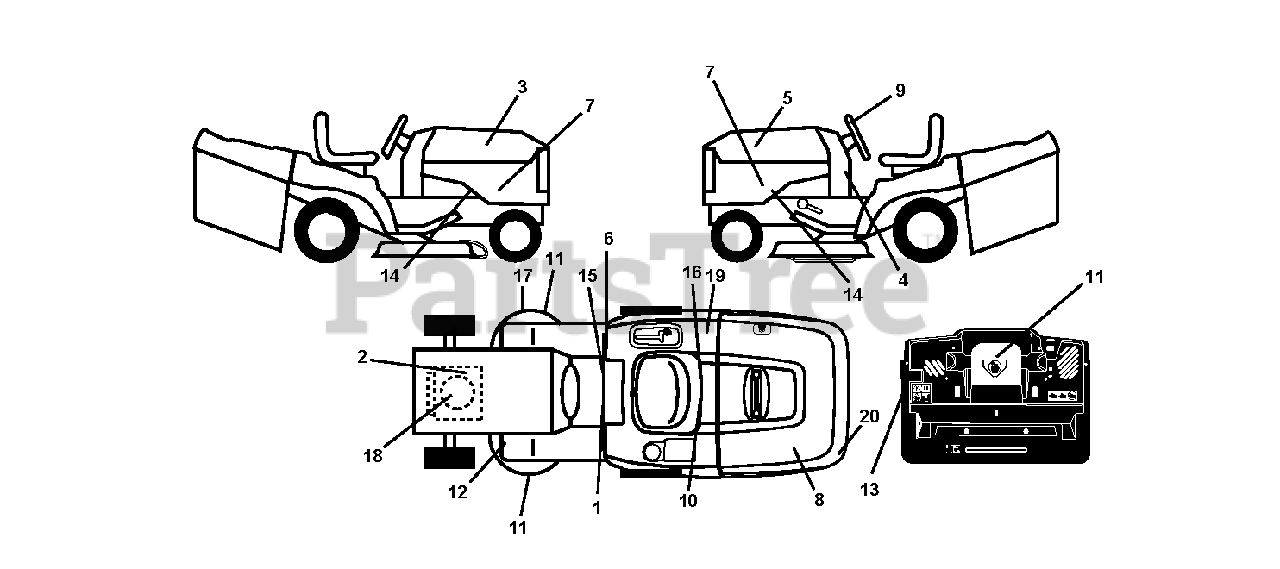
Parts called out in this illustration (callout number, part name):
6	DECAL.80 DBA.AUSTRALIA
10	DECAL BTRY SYMBOLS
11	DECAL.INTERNATIONL.CUTFINGER
15	DECAL PARK BRAKE
16	DECAL.BYPASS.FENDER.CRD.LT.YT
